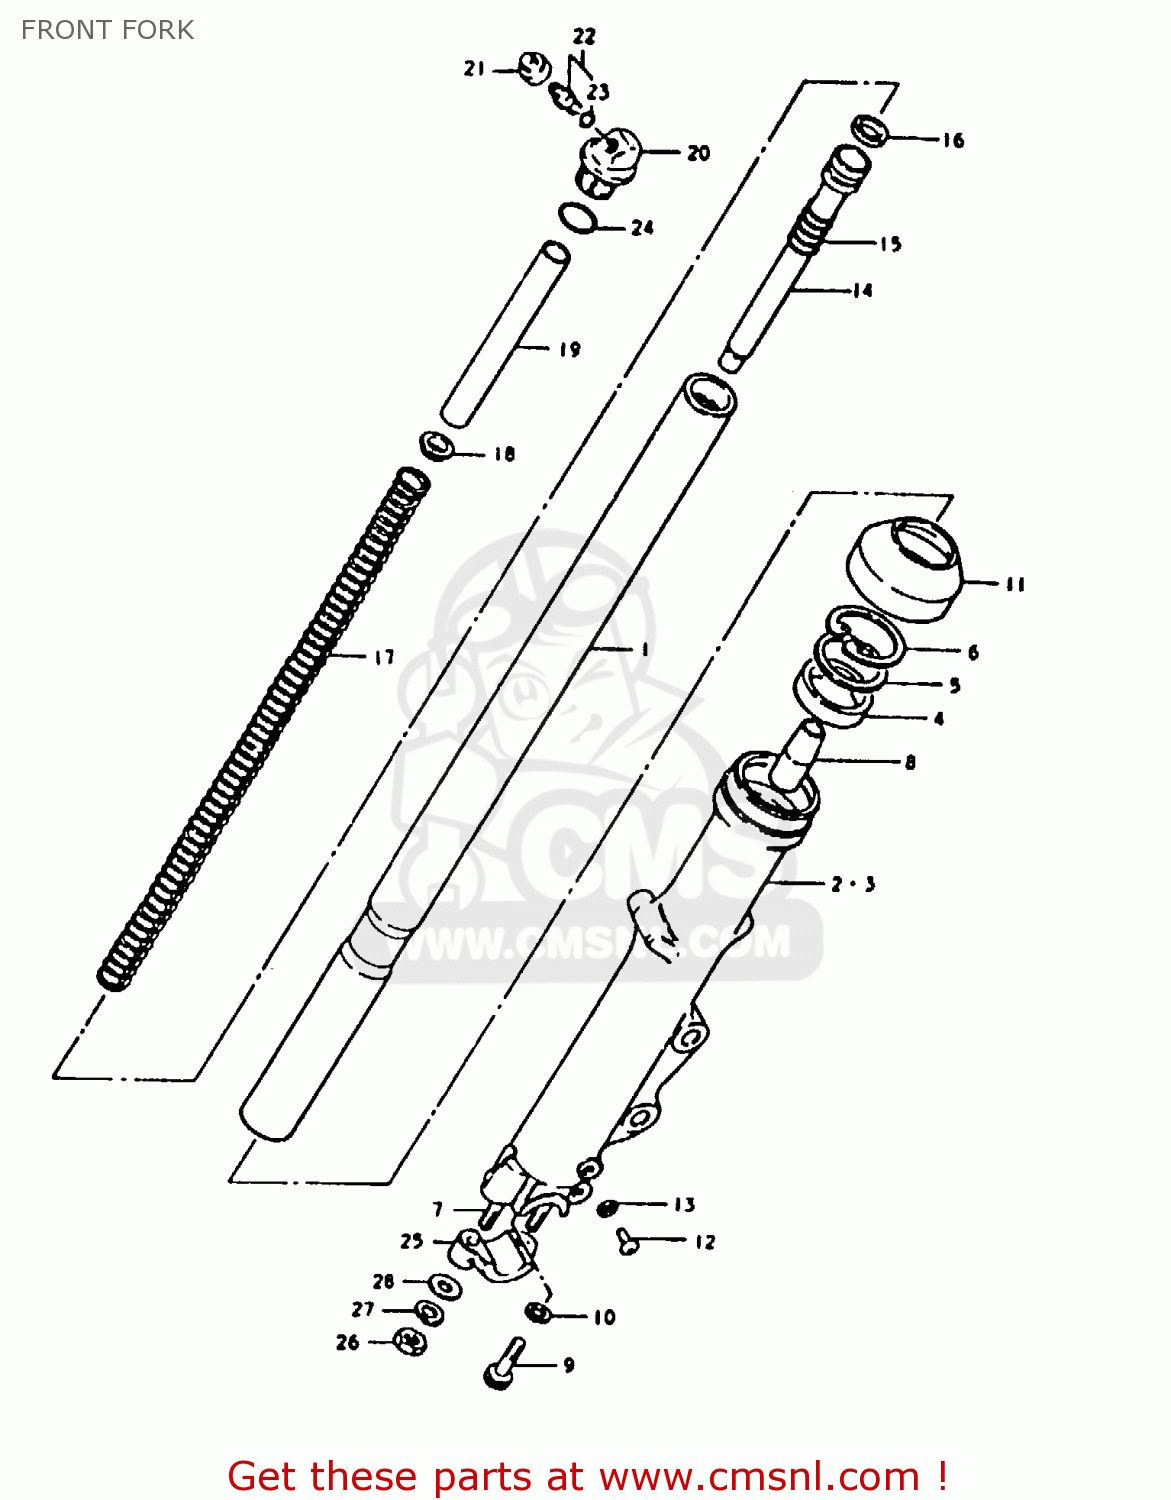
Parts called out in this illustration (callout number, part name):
1	TUBE,FORK,INNER
2	TUBE,FORK,OUTER,RIGHT
3	TUBE,OUTER,LEFT
4	OIL SEAL,FRONT FORK
5	WASHER. FRONT FORK
6	CIRCLIP,FORK OIL SEAL
7	STUD BOLT
8	PIECE,OIL LOCK
9	BOLT,FORK CYLINDER(10X25)
10	GASKET (NAS)
11	SEAL,DUST
12	SCREW
13	GASKET,DRAIN,PLUG (NAS)
14	CYLINDER,FRONT FORK
15	SPRING,REBOUND
16	RING,PISTON
17	SPRING,MAIN
18	GUIDE,FRONT FORK SPRING C
19	SPACER,FRONT FORK SPRING
20	CAP
21	CAP,VALVE
22	VALVE
23	O RING
24	O RING
25	HOLDER,AXLE
26	NUT (8MM)
27	LOCK WASHER
28	WASHER
